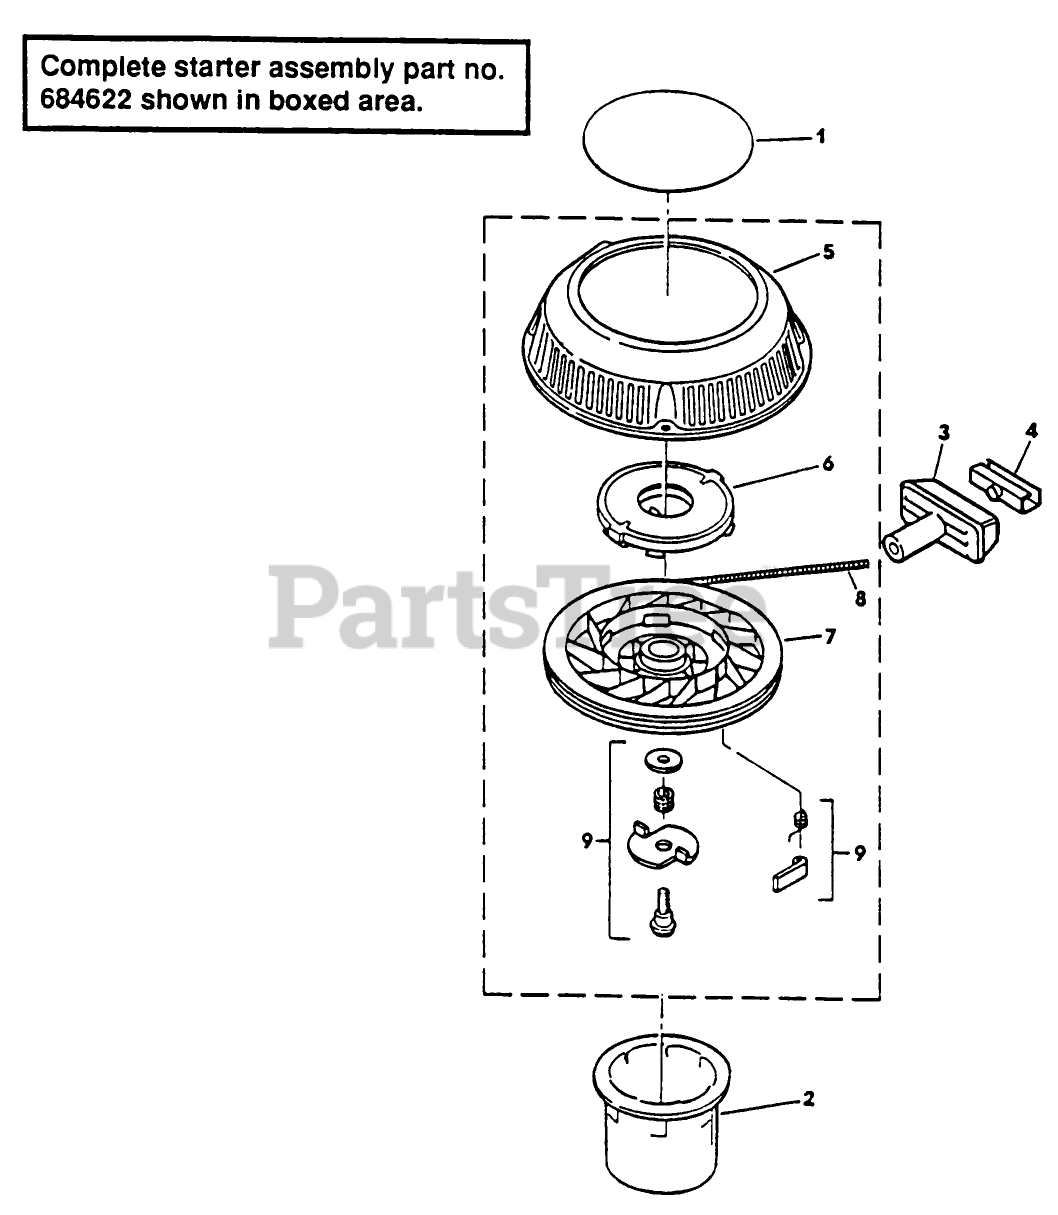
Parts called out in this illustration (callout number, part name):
2	HUB STARTER SM
4	CLIP-STARTER
5	STARTER HOUSING & SHAFT
9	DOG KIT
